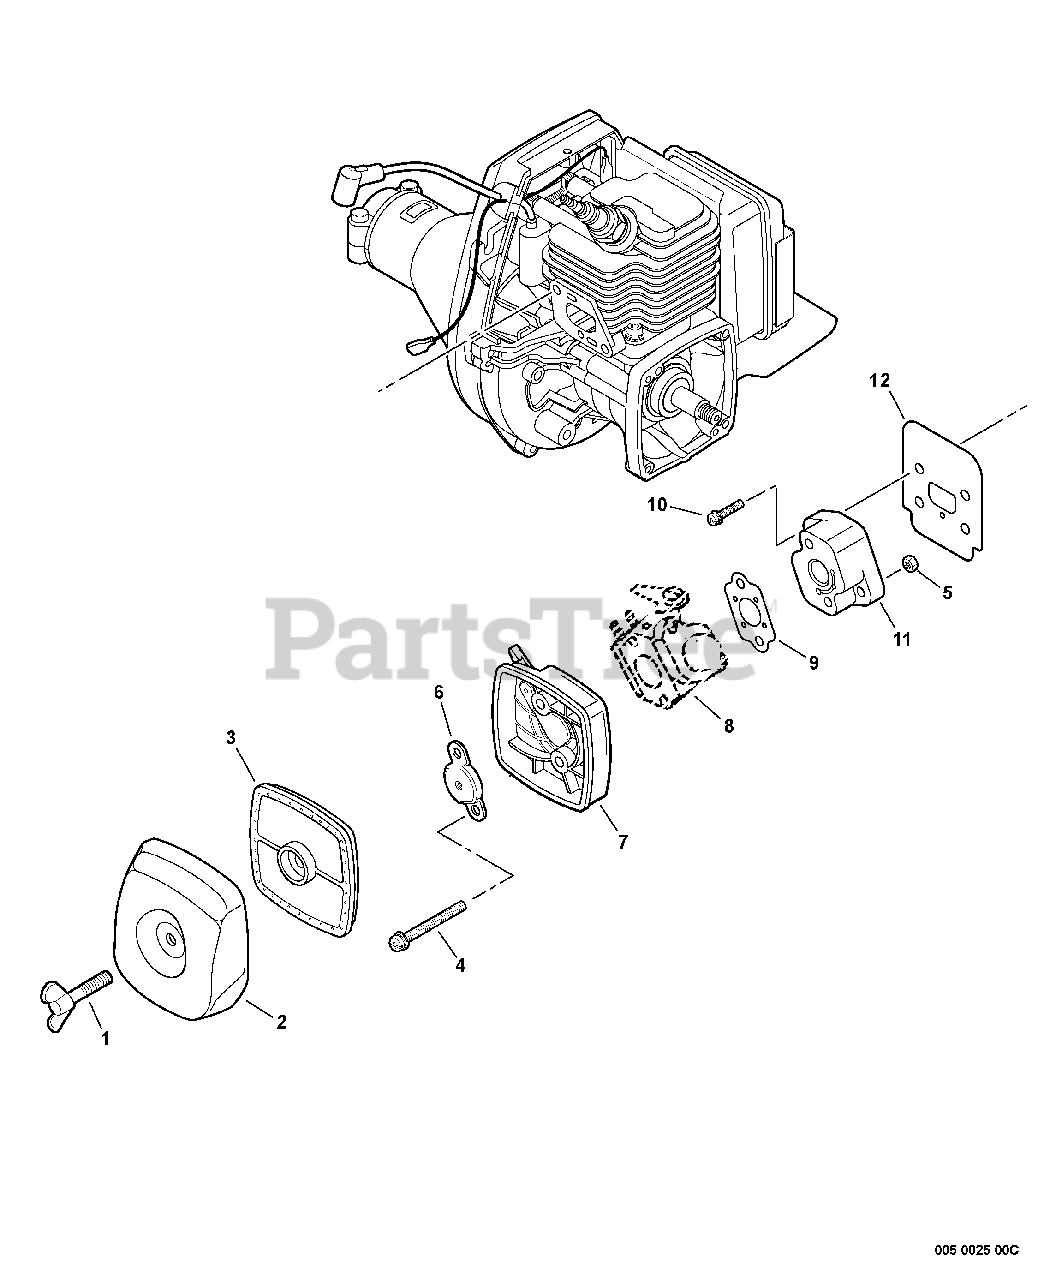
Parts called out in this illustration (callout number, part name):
1	THUMBSCREW
2	COVER, AIR FILTER - GRAY
3	FILTER, AIR - SINGLE LAYER
4	SCREW - 5X65
6	PLATE, PREVENT
7	CASE, AIR FILTER - GRAY
8	CARBURETOR
9	GASKET, INTAKE
10	SCREW - 5X20
11	INSULATOR, INTAKE
12	GASKET, INTAKE
